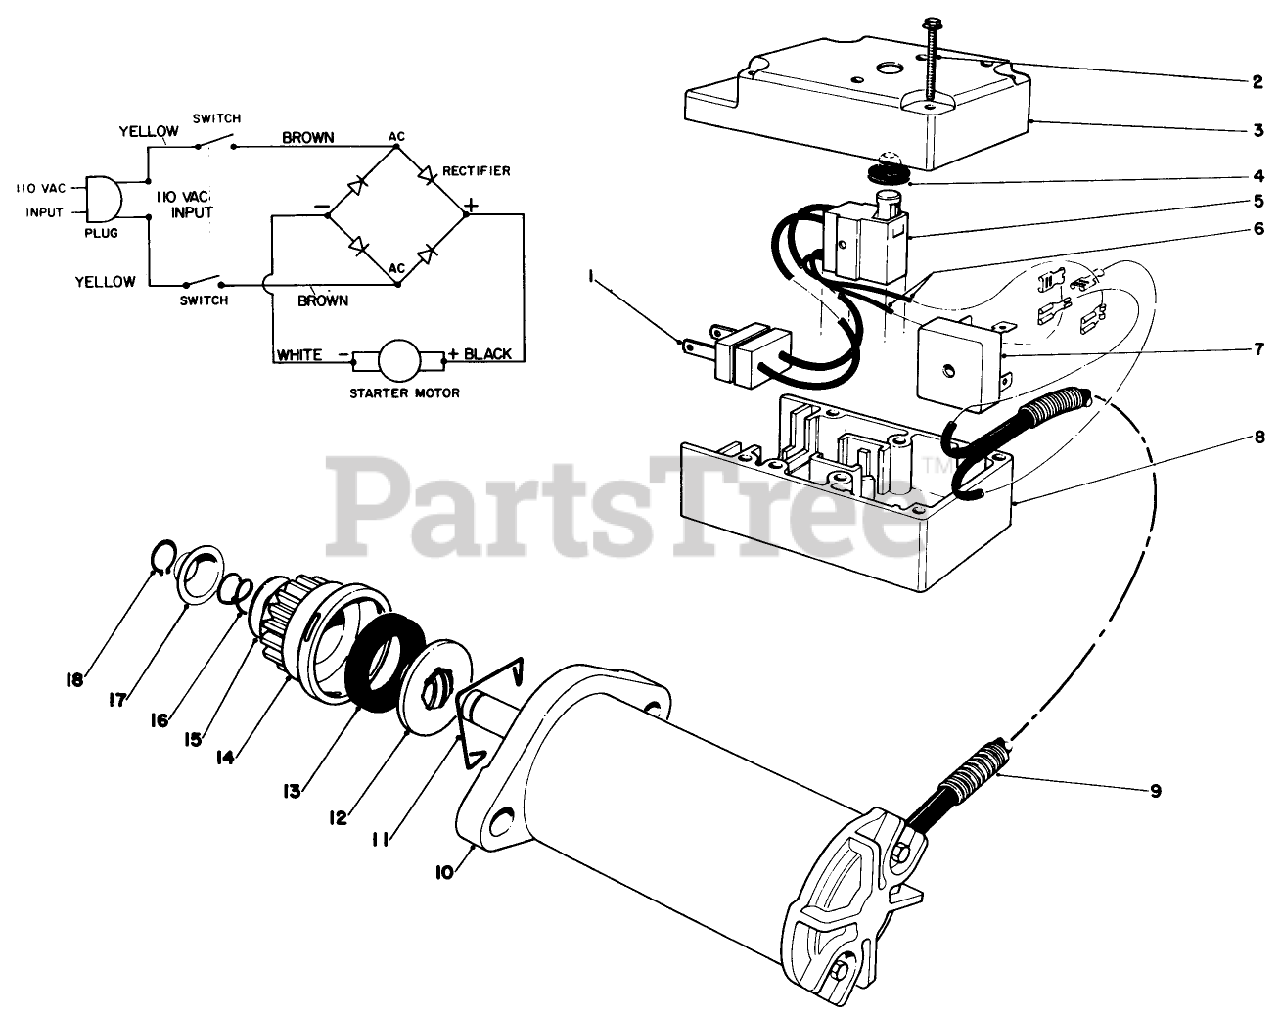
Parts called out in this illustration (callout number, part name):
4	BOOT-SWITCH
5	SWITCH-STARTER
7	RECTIFIER-BRIDGE
8	SWITCH BOX BASE
10	SEE SB SNOW #48
11	RETAINING CLIP
12	Nut-Pinion Gear
13	RUBBER RING
14	Gear-Pinion
15	WASHER
16	SPRING-COMPRESSION
17	PINION STOP
18	RING-RETAINING, EXTERNAL
